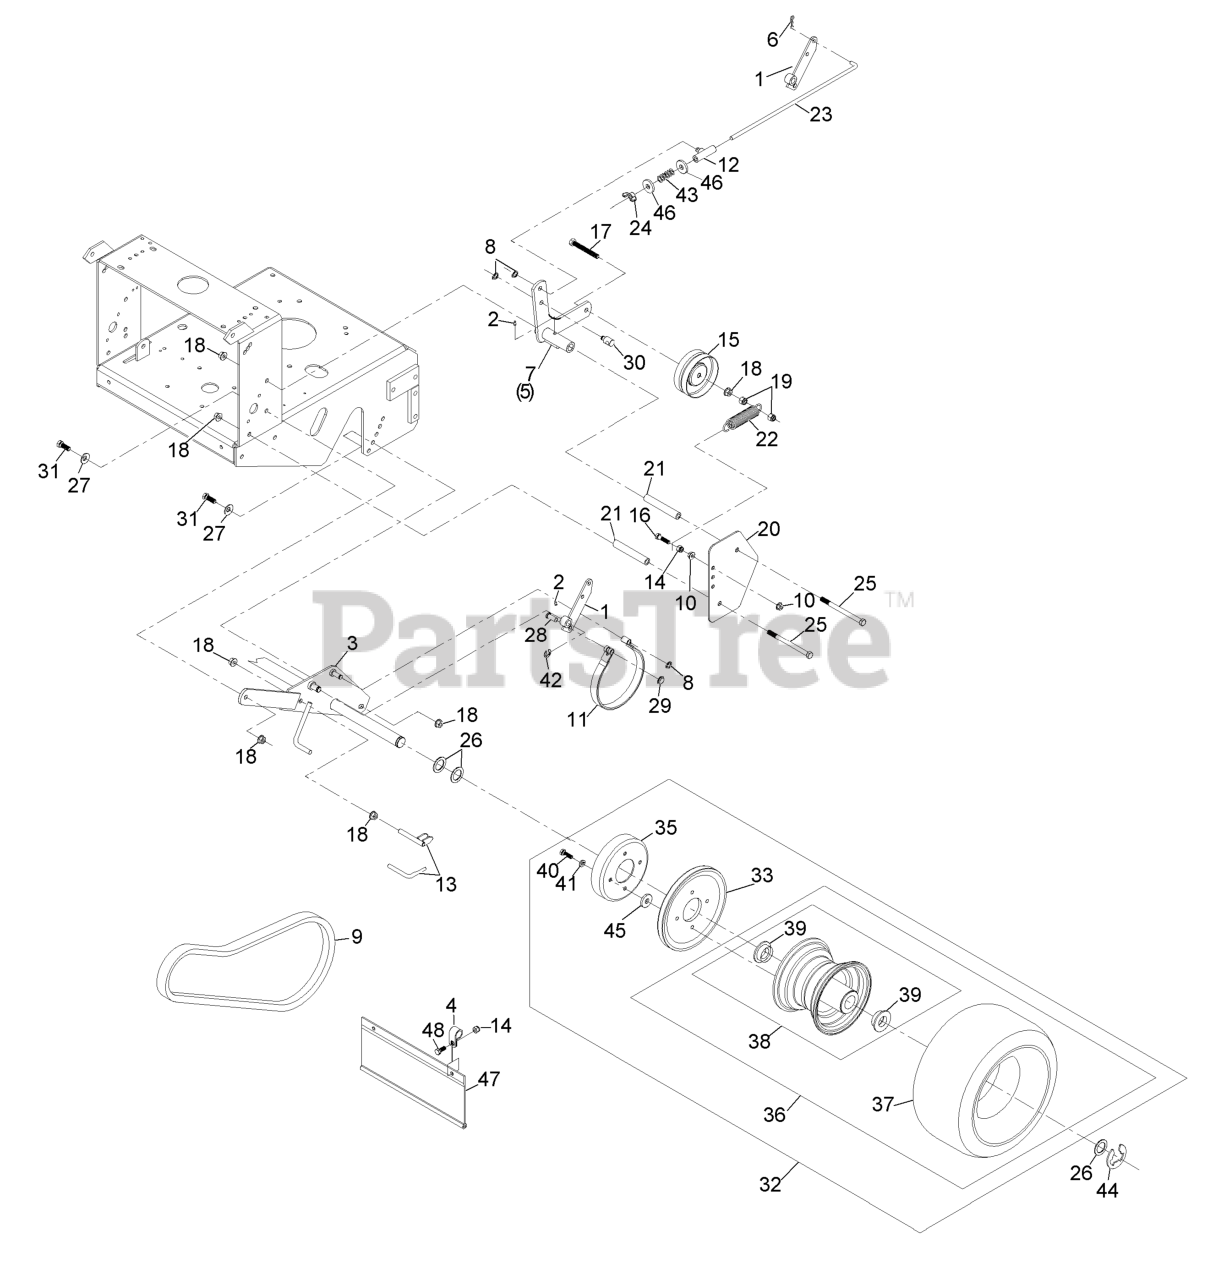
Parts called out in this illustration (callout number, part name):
1	ARM-BRAKE
2	FITTING-GREASE
4	CLAMP-R
5	ARM-IDLER, LH
6	PIN-COTTER
7	ARM-IDLER, RH
8	RING-RETAINING
9	BELT-WHEEL, DRIVE
11	BAND-BRAKE
12	SWIVEL-BRAKE
13	SCRAPER
14	NUT-LOCK, NI
15	IDLER-WHEEL, DRIVE
16	SCREW-HH
17	SCREW-HH
18	NUT-HHF, WHIZ
19	NUT-LOCK, NI
20	SHIELD-WHEEL, DRIVE
21	SPACER-SHIELD
22	SPRING-EXTENSION
23	LINKAGE-BRAKE
24	WINGNUT-NYLOCK
25	SCREW-HH
26	WASHER-SPACER
27	WASHER-BELLEVILLE
28	PIN-CLEVIS
29	RING-RETAIN,PUSH,EXT,FLAT
30	SWIVEL-LEVER, DRIVE
31	SCREW-HH
32	DRIVE WHEEL ASM
33	SHEAVE-WHEEL, DRIVE
35	DRUM-BRAKE
36	WHEEL AND TIRE ASM
38	WHEEL AND HUB ASM
39	BEARING-FLANGED
40	SCREW-HH
41	WASHER-LOCK
42	RING-RETAINING, EXTERNAL
43	SPRING-COMPRESSION
44	RING-SNAP
46	WASHER-PLAIN
47	SHIELD-TRAILING
48	SCREW-HH
